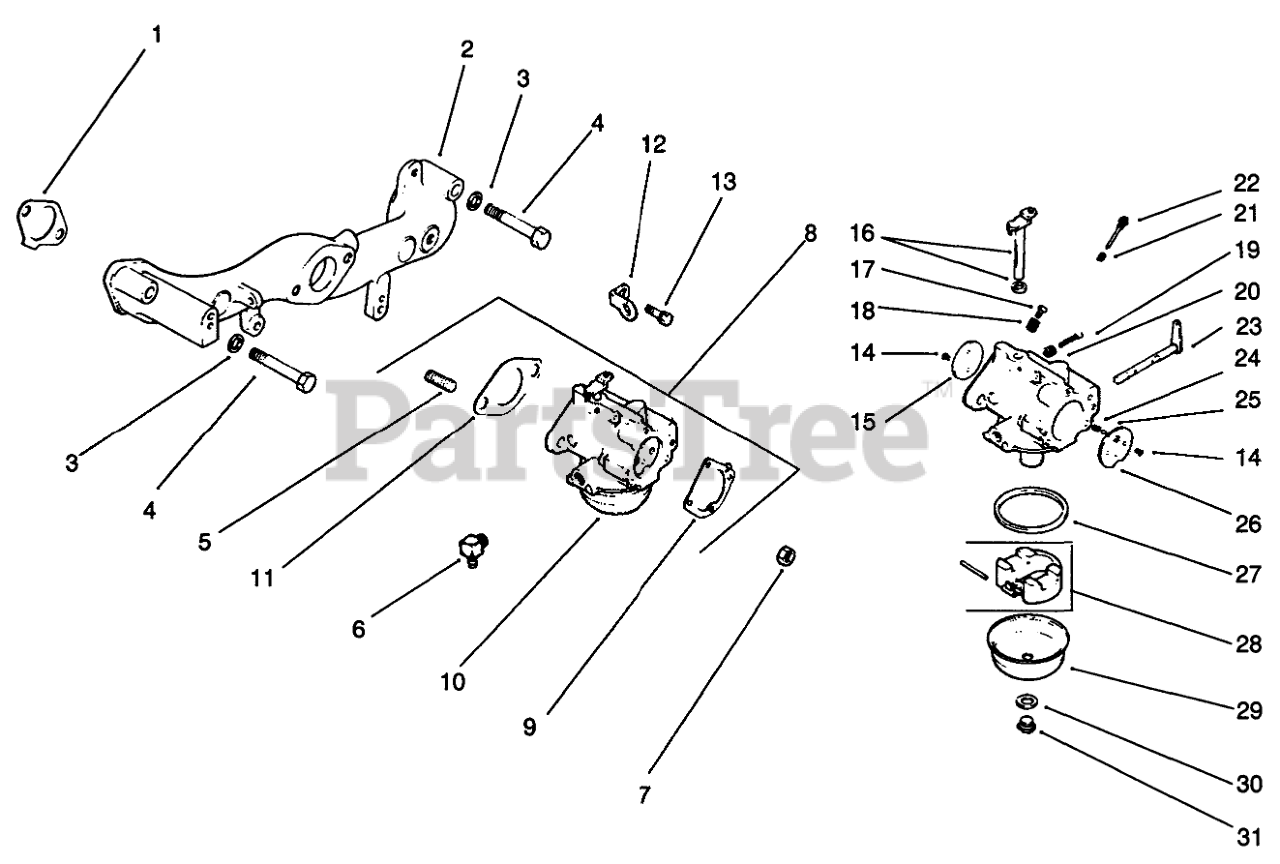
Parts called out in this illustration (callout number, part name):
1	Gasket-Intake
2	Manifold-Intake
3	Screw
4	Screw
5	Stud
6	Connector-90deg.
7	Nut
8	Carburetor Kit W/Linkage (Incl. Ref. #9-10, & 12-27)
9	Gasket
10	Carburetor Assembly Ref.
11	Gasket
12	Strap Lifting
13	Screw
14	Screw-Throttle Plate
15	Plate-Throttle
16	Shaft Assembly
17	Valve-Needle
18	Spring
19	Screw
20	Spring
22	Needle-Main Fuel
23	Lever-Choke
24	Spring-Choke
25	Ball-Choke
26	Plate-Choke
27	Bowl-Gasket
28	Kit-Float
29	Bowl
30	Gasket-Bowl
31	Screw-Bowl
